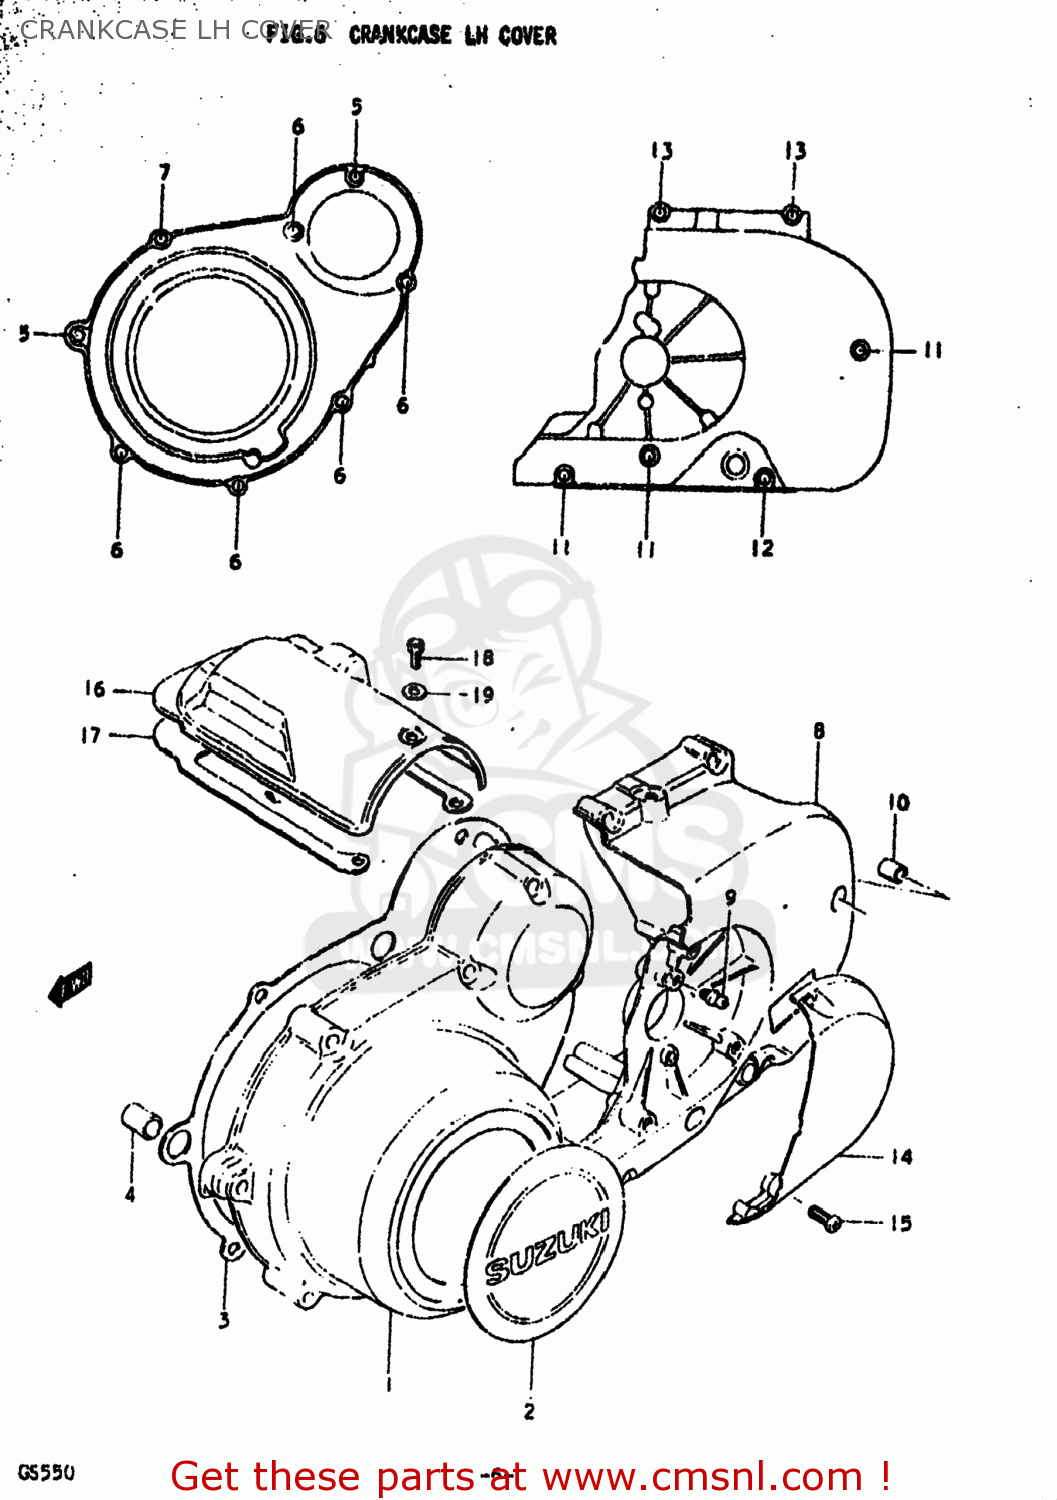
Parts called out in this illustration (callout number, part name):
1	COVER
2	EMBLEM
3	GASKET,MAGNETO COVER (MCA)
4	PIN
5	SCREW (6X45)
6	SCREW
7	SCREW (6X35)
8	CRANKCASE SET
9	NIPPLE
10	PIN
11	SCREW
12	SCREW 6X80
13	SCREW
14	CAP,CLUTCH RELEASE ADJUST
15	SCREW
16	COVER,STARTER MOTOR
17	GASKET
18	BOLT
19	WASHER
